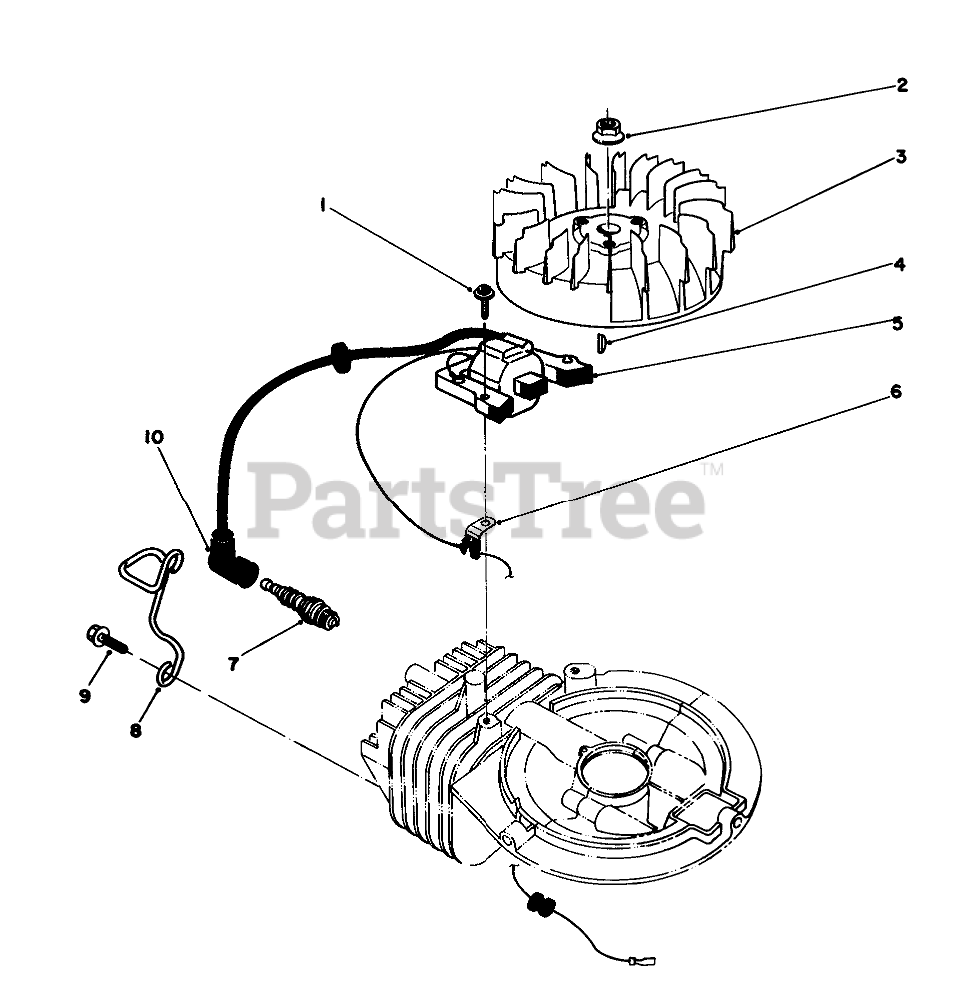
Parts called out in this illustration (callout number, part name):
1	SCREW
3	FLYWHEEL
5	COIL-MAGNETO
6	CLAMP
7	Sparkplug
8	PROTECTOR-PLUG
9	SCREW
10	CAP-SPARKPLUG
